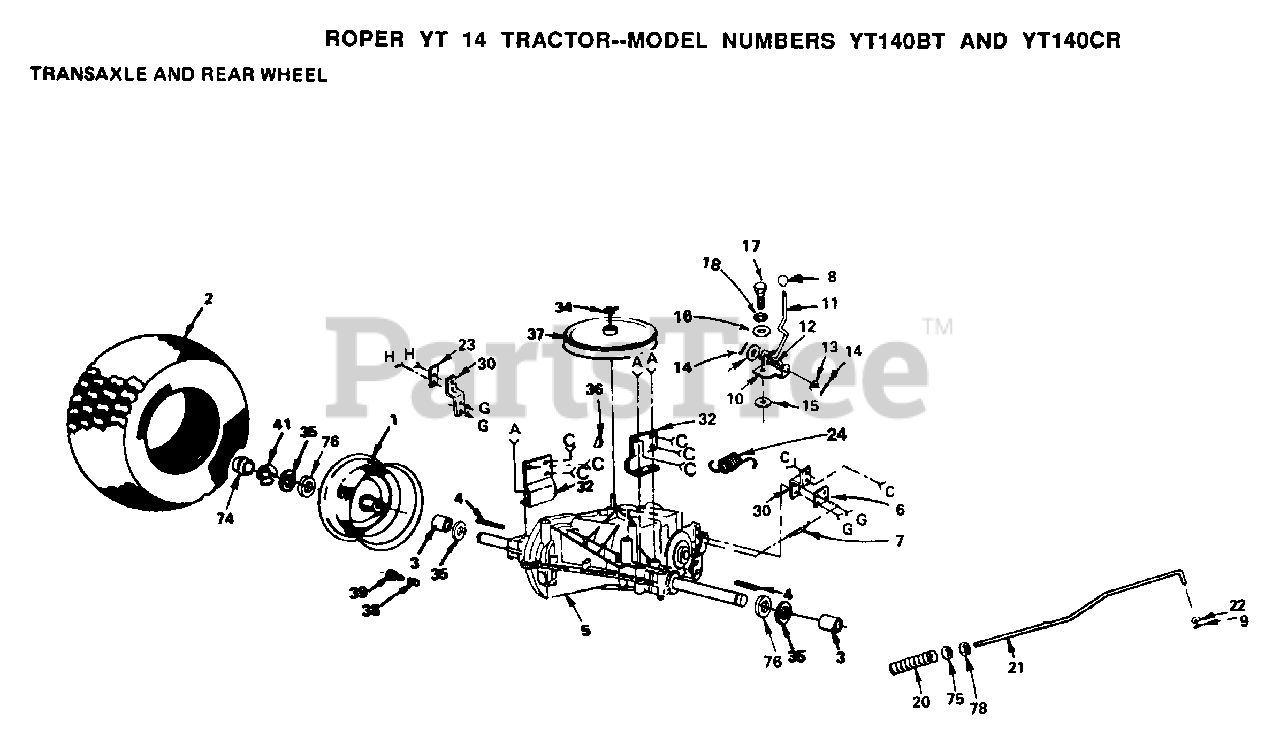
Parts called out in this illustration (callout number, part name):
3	SPACER LT
6	BRACKET-SPRING LT
7	SPRING-EXT LT
8	KNOB T (1/2-HOLE)
9	COTTER PIN
10	PLATE SHIFT LT
12	SPRING LT
13	WASHER
14	PIN COTTER 1/8
15	WASH-SHFT PLT LT
16	WASHER LT
18	LOCKWASHER
20	SPRING ROD LT
21	BRAKE ROD LT
22	WASHER
23	PLATE-STRAP LT
30	"STRAP, TORQUE LT"
32	BRACKET LT
38	VALVE CAP
39	VALVE STEM LT
41	E-RING LT
74	HUB CAP
78	NUT
